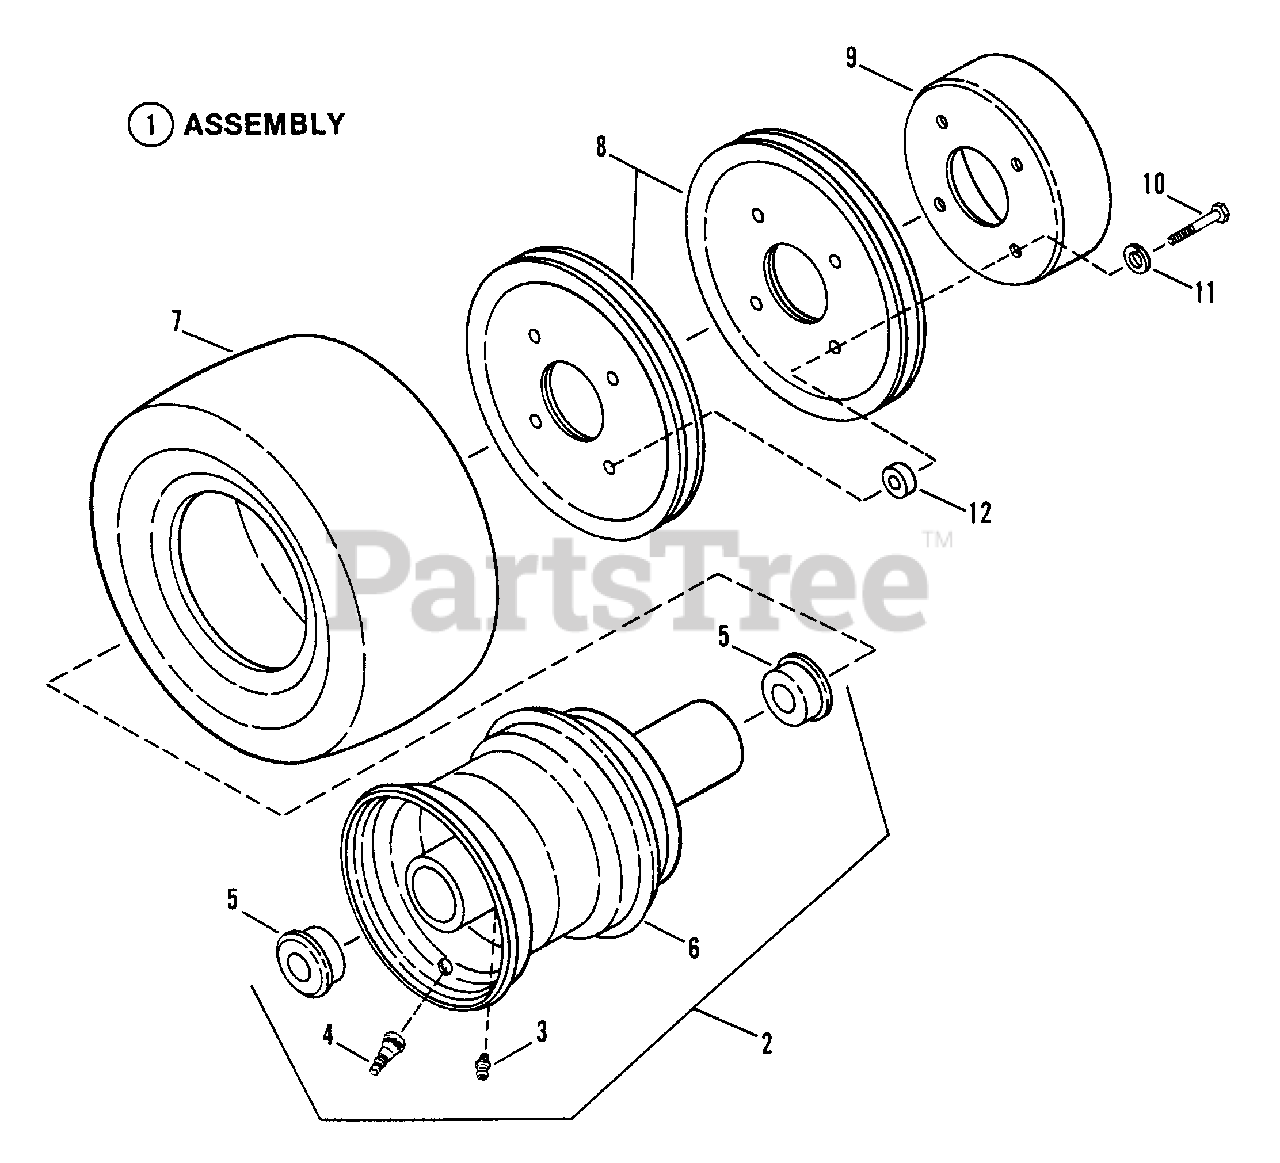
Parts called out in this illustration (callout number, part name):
1	ASSEMBLY, Rear Tire & Rim
2	ASSEMBLY, Rim
3	FITTING, Lube
4	VALVE, Air (Snap-In)
5	BEARING, Wheel
6	RIM
7	TIRE, 6 50 x 13-6 Tubeless
8	PULLEY, 8"
9	DRUM, Brake
10	SCREW, 5/16-18 x 1-1/2" Hex Head Cap
11	WASHER, 5/16" Split Lock
12	SPACER
